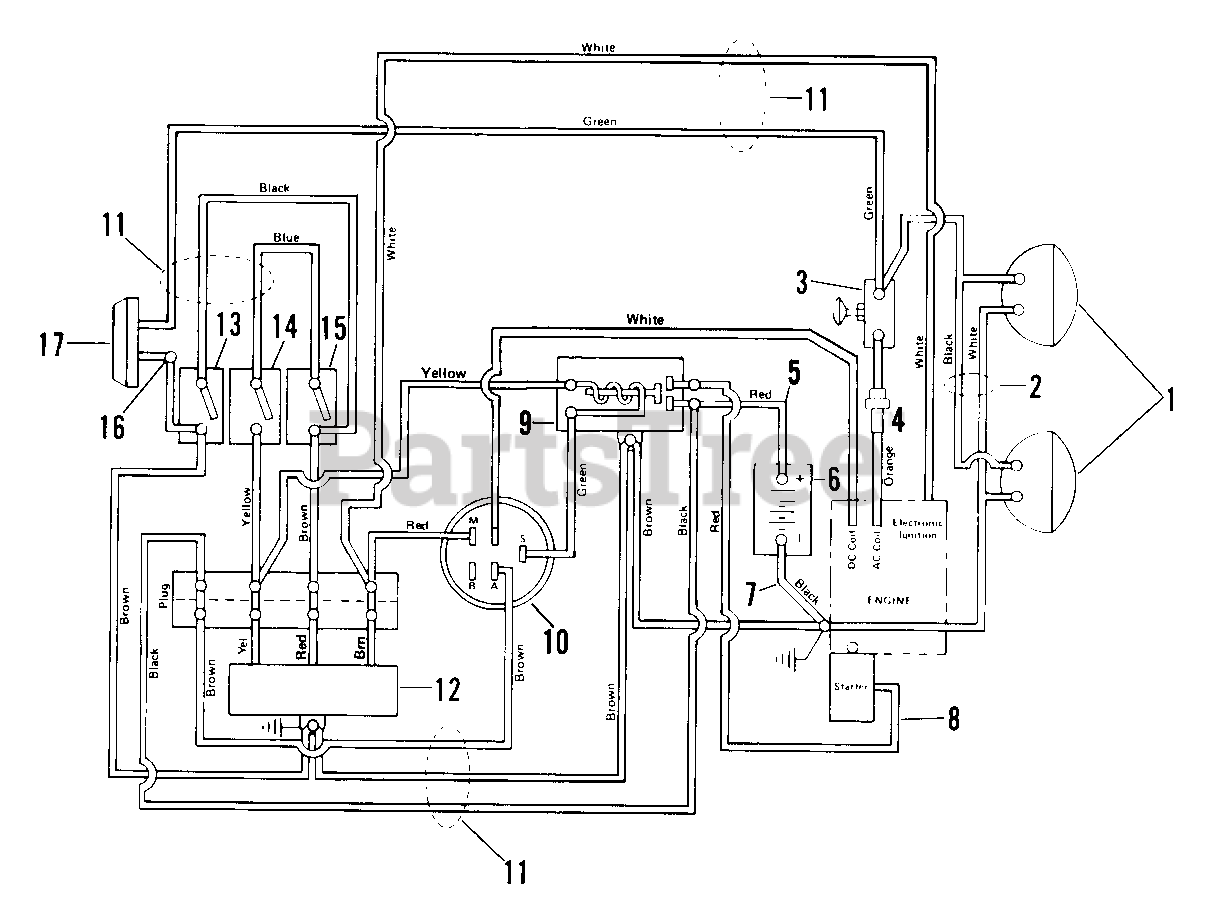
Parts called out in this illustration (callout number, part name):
1	HEAD LIGHT
2	WIRE HARNESS - HEADLIGHT
3	LIGHT SWITCH
4	6 AMP FUSE
5	STARTER CABLE
5	CABLE
6	BATTERY
7	GROUND CABLE
7	CABLE-GROUND
8	STARTER CABLE 16"
8	CABLE STARTER
9	SOLENOID
10	IGNITION SWITCH ASSEMBLY
11	WIRE HARNESS 11HP
11	WIRE HARNESS
12	MODULE
13	SWITCH SEAT
14	SWITCH INTERLOCK
15	SWITCH-NEUTRAL START N.O.
15	SAFETY SWITCH
16	MALE DISCONNECT ADAPTER
17	TAIL LIGHT ASSEMBLY W/BULLET
